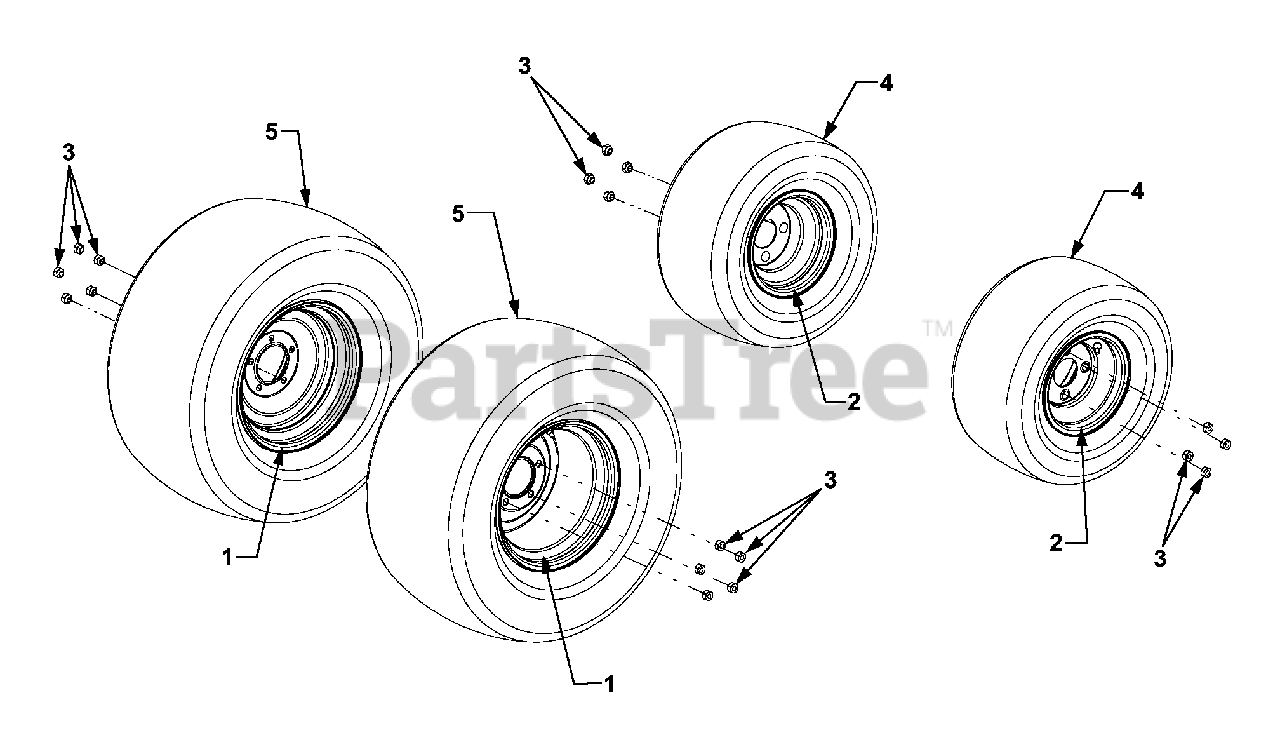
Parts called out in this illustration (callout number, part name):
1	Rim Assembly
2	Rim Assembly, Turf Tire
2	Rim Assembly, Ag Tire
3	Nut, Lug, 7/16-14
4	Tire, Turf, 18 x 8.5 x 8
4	Tire, Ag, 18 x 9.5 x 8
5	Tire, Turf, 26 x 12.0 x 12
